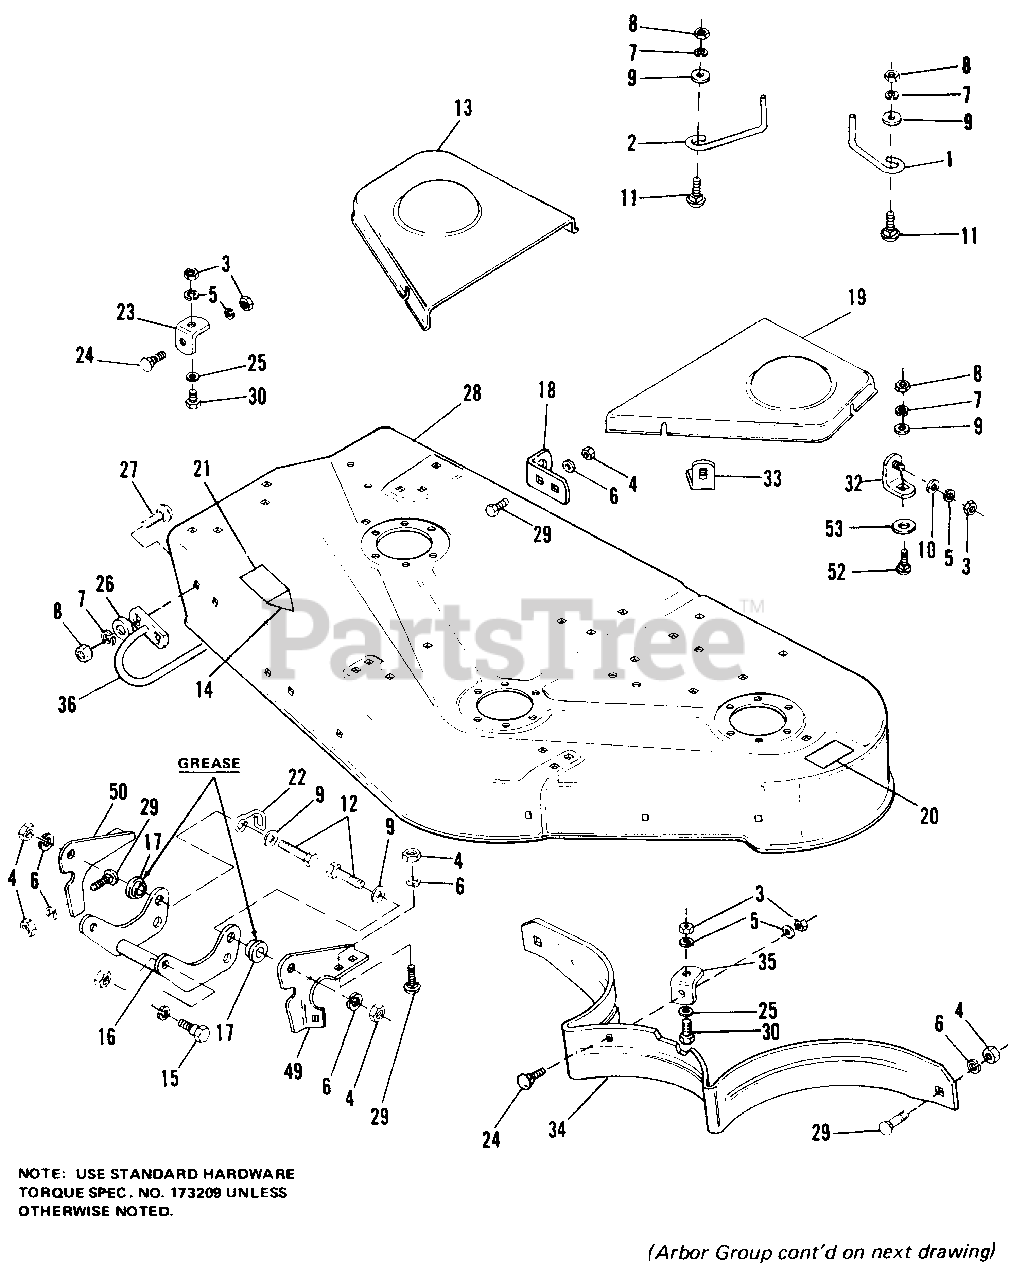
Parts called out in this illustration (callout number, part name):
2	STOP, Belt
3	NUT, Hex, 1/4-20
4	NUT, Hex, 3/8-16
5	LOCKWASHER, 1/4
6	LOCKWASHER, 3/8
7	LOCKWASHER, 5/16
8	NUT, Hex, 5/16-18
9	WASHER, 5/16
10	WASHER, 1/4
11	BOLT, Carriage, 5/16-18 x 3/4
12	CAPSCREW, Hex Hd., 3/8-16 x 1-1/2
13	COVER, Arbor, R.H.
14	DECAL, OPEI
15	BOLT, Shoulder
16	ARM ASSY., Front
18	BRACKET, Roller, Support
19	COVER, Arbor, L.H.
20	DECAL, Warning
21	DECAL, Warning
22	GUIDE, Cable
23	CLIP, Guard & Baffle
24	BOLT, Carriage, 1/4-20 x 5/8
25	WASHER, 1/4
26	WASHER, 1 1/32 x 1
27	BOLT, Carriage, 5/16-18 x 1
28	HOUSING, Mower, 42"
29	BOLT, Carriage, 3/8-16 x 3/4
30	CAPSCREW, Hex Hd., 1/4-20 x 3/4
32	LEG ASSY., Cover
33	LEG ASSY., Cover
34	BAFFLE
35	CLIP, Baffle
36	GUARD & BAFFLE ASSY
49	BRACKET, Mower Front, L.H.
50	BRACKET, Mower Front, R.H.
52	BOLT, Carriage, 5/16-18 x 1
53	WASHER, Special
